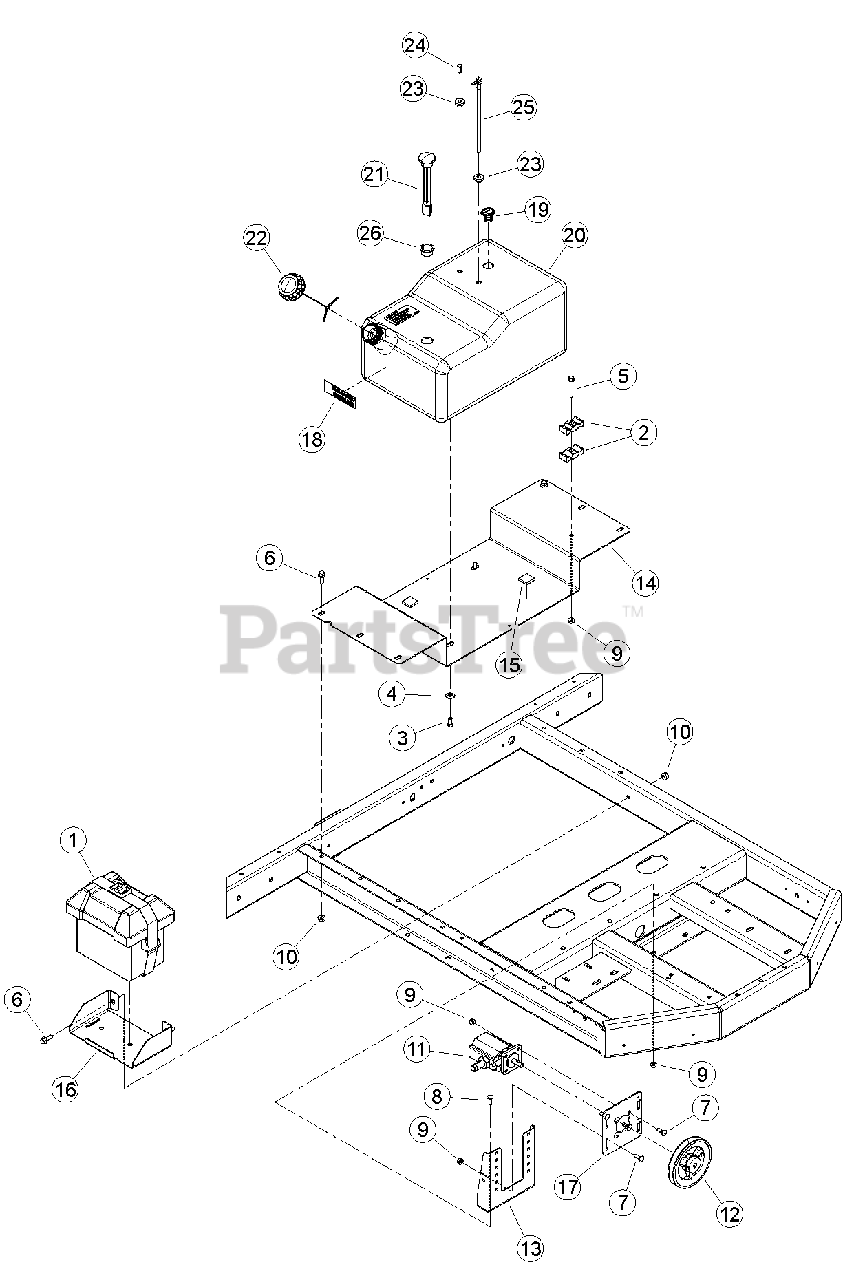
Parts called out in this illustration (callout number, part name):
1	BOX, SMALL BATTERY
2	CLAMP, PLASTIC HOSE
3	BOLT, 3/8 X 3/4 GR5 HEX CAPSCREW ZP
4	WASHER, 3/8 FLAT
5	BOLT, 5/16 X 2-1/4 FLANGE NC
6	BOLT, 3/8 X 1 FLANGE NC
7	BOLT, 5/16-18 X 1 GR5 CRG
8	BOLT, 5/16-18 X 7/8 GR5 CRG
9	NUT, 5/16-18 NYLOCK FLANGE
10	NUT, 3/8-16 NYLOCK FLANGE
11	PUMP, 2 STAGE CW HI/LO 0.605 DISP.
12	PULLEY, 5.6 - 1/2" BORE FHP B
13	BRACKET, MOUNT HYDRAULIC PUMP
14	BASE, 9.25 GAL NYLON TANK
15	PAD, FOAM FUEL TANK DAMPER
16	BRACKET, BATTERY HOLDER
17	PLATE, HYDRAULIC PUMP
18	DECAL, UNLEADED GASOLINE
19	VALVE, ROLL OVER
20	TANK, ROTOMOLDED FUEL
21	GAUGE, FUEL LEVEL KELCH 100
22	CAP, NON-VENTED EPA/CARB APPROVED
23	GROMMET, TANK FITTING
24	PLUG, TANK VENT
25	FITTING, TANK FUEL PICK-UP TUBE
26	GROMMET, KELCH 100 GAUGE
